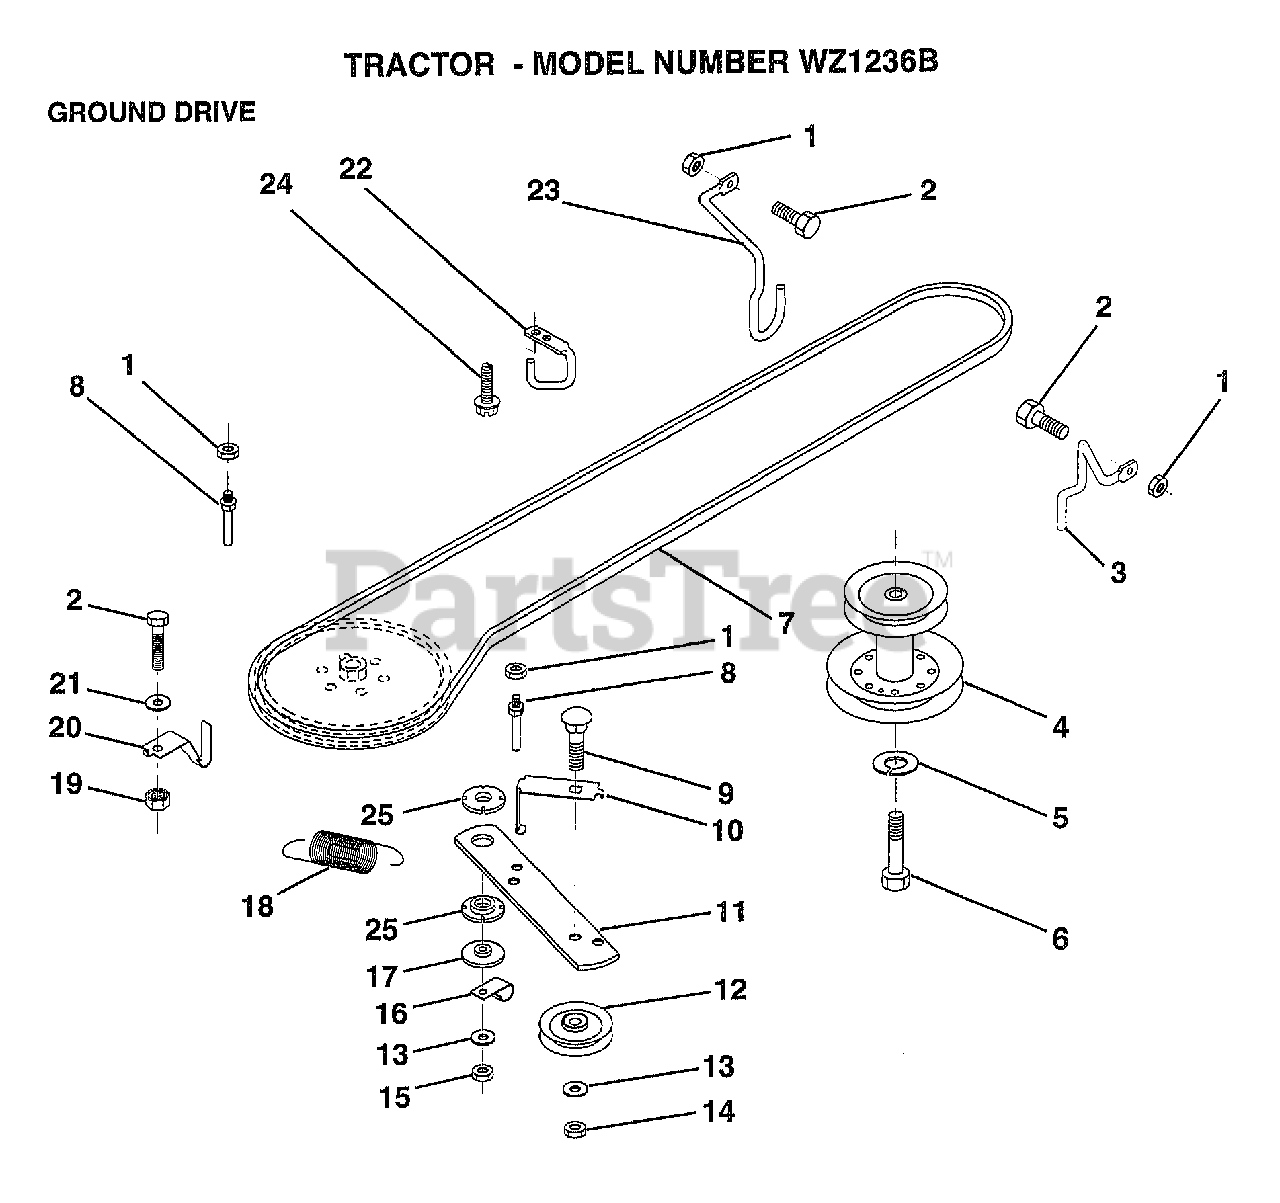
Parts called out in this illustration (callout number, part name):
2	BOLT
3	KEEPER RH
4	PULLEY.ENGINE.LR
5	LOCKWASHER
6	HEX BOLT
7	V BELT
8	"KEEPER,DRIVE BELT"
9	BOLT
10	"KEEP,IDLER DR BEL"
11	ARM-IDLER.DR.GRND
12	PULLEY.IDLER.FLAT
13	WASHER
14	LOCKNUT
16	"CLIP,INSULATOR"
17	SPACER
20	KEEPER.BELT.T/A
21	WASHER
22	"KEEPER,FRA DR BEL"
23	KEEPER MOWER LH
24	SCREW
25	BUSHING.NYLON
